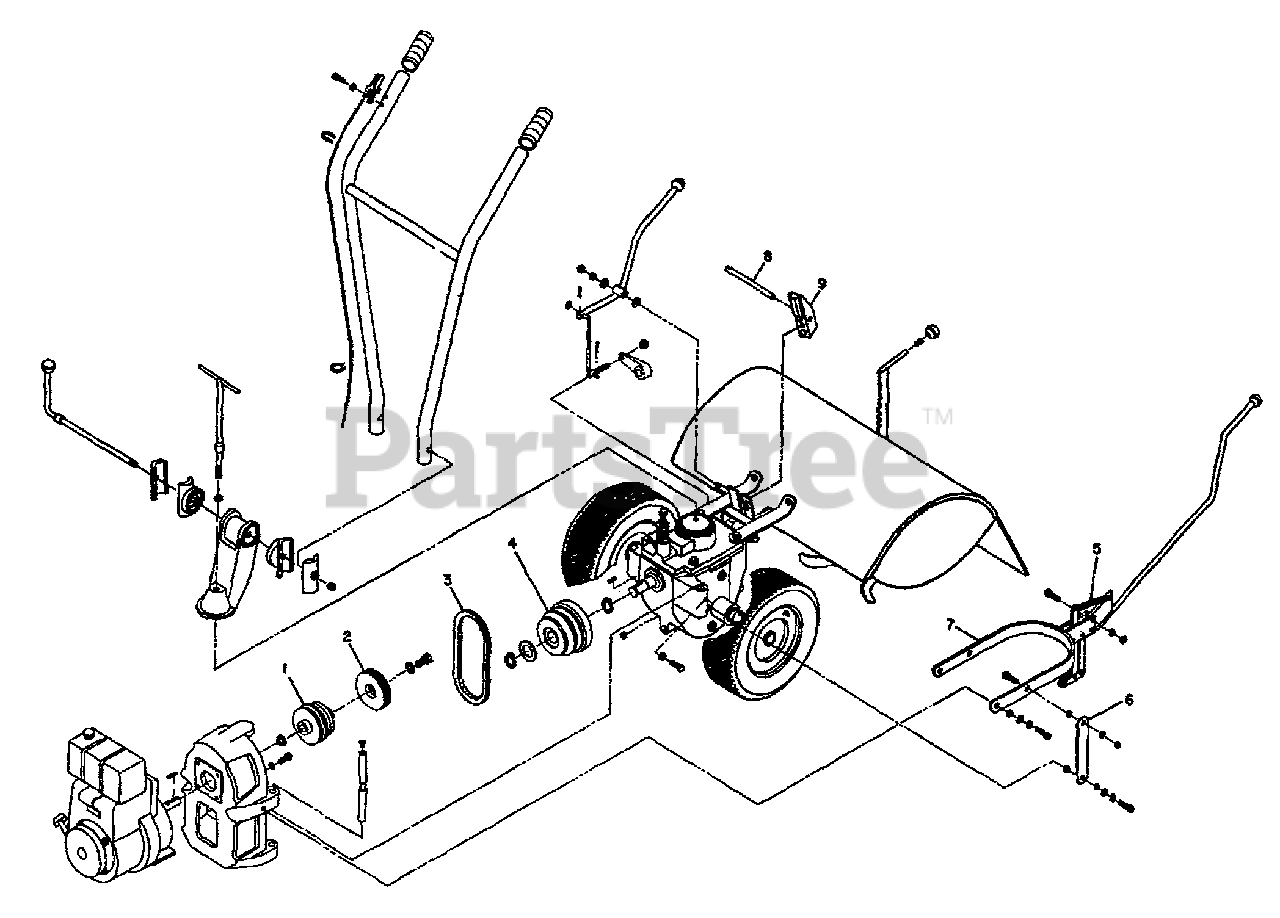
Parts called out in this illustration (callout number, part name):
1	PULLEY-ENG MACH
2	KIT-ADJ BLOCK/REV DISC
3	BELT-V
4	PULLEY-TRANS-MACH
5	SPRING-.436 X 3.25
6	BAR-CLUTCH YOKE
7	KIT-LEVER FWD/REV-HORSE 2
8	BAR-ADJUST
9	KIT-ADJ BLOCK 4 SP
